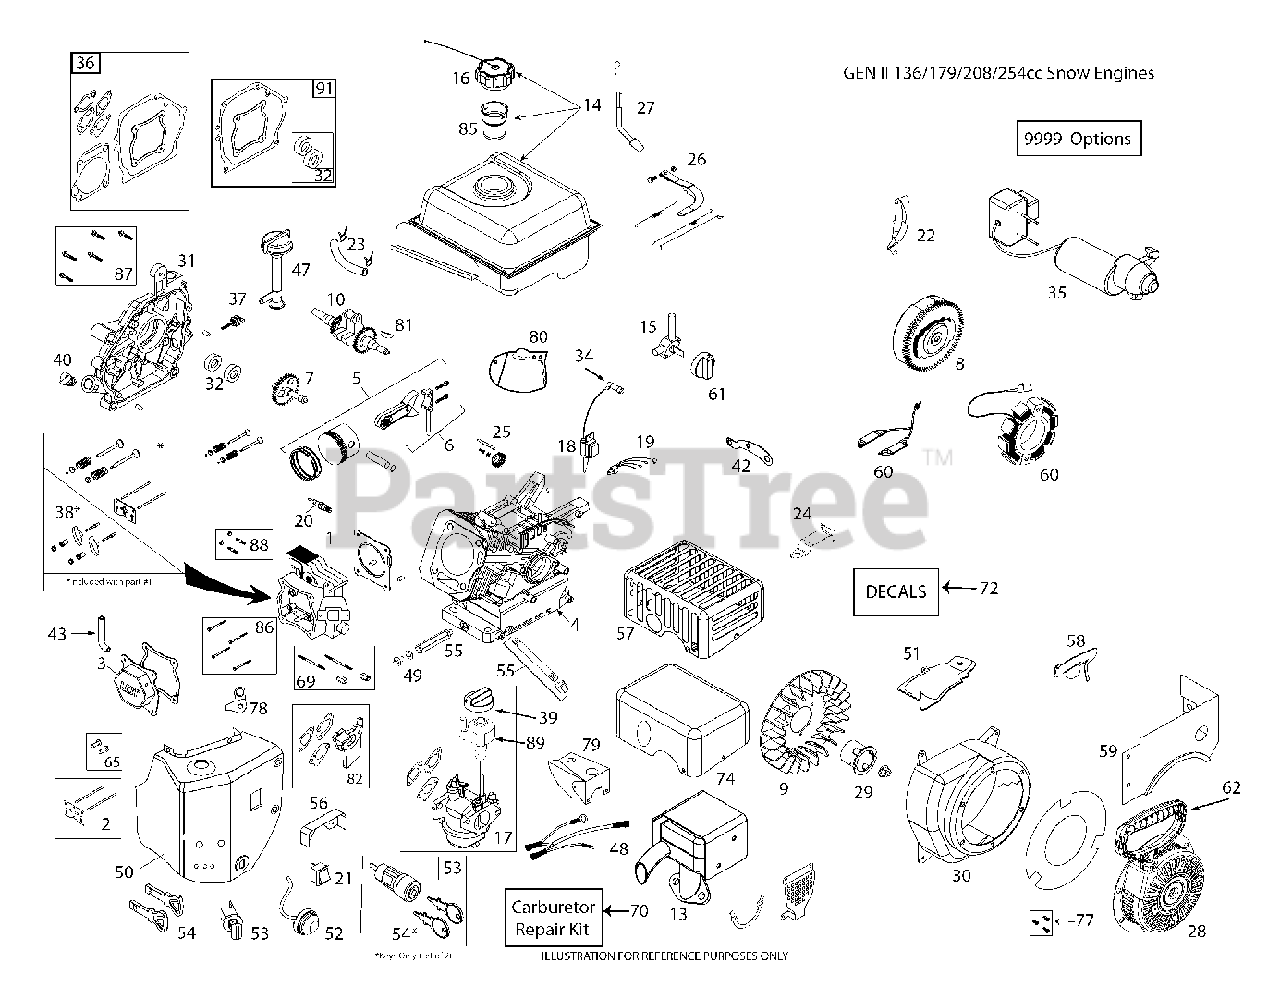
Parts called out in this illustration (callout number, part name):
1	CYLINDER.HEAD.ASM.W/GASKET.254
2	KIT.PUSH.ROD.&.PLATE.W/VC.GASK
3	COVER.VALVE.W/GASKET.254CC
5	PISTON.&.ROD ASSEM.254CC
7	CAMSHAFT.MCR.W/GASKET.254CC
8	FLYWHEEL.ELEC.STRT.(8.MAGNETS)
9	KIT.COOLNG.FAN.SERV(SK208-4000
10	CRANKSHAFT.KEYED(#18).SNOW.254
13	MUFFLER ASSY LCT.GEN 2 SNOW
14	FUEL.TANK.SNOW.2.7L.BLACK.254C
15	FUEL.PETCOCK.SNOW(SKSN4900)
16	FUEL CAP OVERSIZED CLICK STYLE
17	CARBURETOR.SNOW.(L15).254CC
18	COIL.ING.CDI.HI TEMP.SKSNO416.
20	PLUG.SPARK.PLAT.SKSN2404.1
21	SWITCH.ON/OFF(SKSN-0403)
22	SHIELD.FLYWHEEL.ELEC.STRT.208C
23	FUEL HOSE KIT
24	BRACKET.SPEED.CNTRL.FIXED.254C
25	GOVENOR.GEARS ASM(SK2082900)
26	KIT.GOVERNOR.ARM.&.LINK.254CC
27	KIT.GOVERNOR.CRANK(SK208-3100)
28	RECOIL.STRT.ROUND(BLK) SNOW
29	STRTER.CUP(NON-SLOT)SKSN0601.2
30	BLOWER HOUSING ASSEMBLY
31	CRANKCASE.CVR.PRESS.IN.HI-OIL.
32	KIT.SEAL.OIL.2.PIECES.254CC
34	SPARK.PLUG.BOOT.SNW,SKSN4691.1
35	ELEC.START.GEN2.SKSN0400.2
36	KIT.ENGINE.GASKET.254CC
38	KIT.ROCKER.ARM.W/GASKET.254CC
39	CHOKE.KNOW.SNOW(SKSN4500)
40	NON REMOVABLE PLUG
43	TUBE.BREATHER.LCT.208
47	High Oil Fill Tube Assembly
48	WIRE.HARNESS(SKSN4406)
49	KIT.OIL.DRAIN.PLUG(SK2089911
50	KIT.HEATER.BOX.SNOW.254CC
51	SHIELD.CYLINDER.COVER.254CC
52	PRIMER.BULB.WITH HOSE (SNOW)
53	SWITH.KEY.ASSEM.SNOW.SINGLE.ST
54	KEY SET(2 KEYS) SKSN0407.1
55	EXTENDED OIL DRAIN TUBE
56	SHIELD.CARBURETOR.VAPOR
58	SHIELD.GOVERNOR.LINKAGE.254CC
59	FUEL TANK SKIRT SHIELD LCT 254
60	208CC 60W ALTERNATOR
61	FUEL KNOB-SNOW
62	HANDLE.RECOIL.DELUXE.LCT
65	TAPPET.KIT.LCT.208CC
69	CARB.STUDS & COUPLING KIT.SNOW
70	CARB.REPAIR.KIT.LCT.SK9900.1
72	Decal Kit, Engine 208CC LCT SK1
77	BOLT.KIT.RECOIL.LCT.ALL.ENGINE
79	COVER.CARBURETOR.SNOW
80	SHIELD.GOVERNOR.LINK.SNOW.254C
81	KEYS.FLYWHEEL.208/414CC.5PACK
82	SPACER.CARBURETOR.208CC.LCT
85	Fuel Tank Strainer, LCT 208cc
86	KIT.BOLT.CYLINDER.HEAD.(4PC)
87	KIT.BOLT.CRANKCASE.COVER.6PC
88	STUD.MUFFLER.KIT.LCT
91	CRANKSHAFT GASKET KIT.LCT
9999	High Altitude Jet, LCT >5000 25
9999	Bolt Kit, LCT
